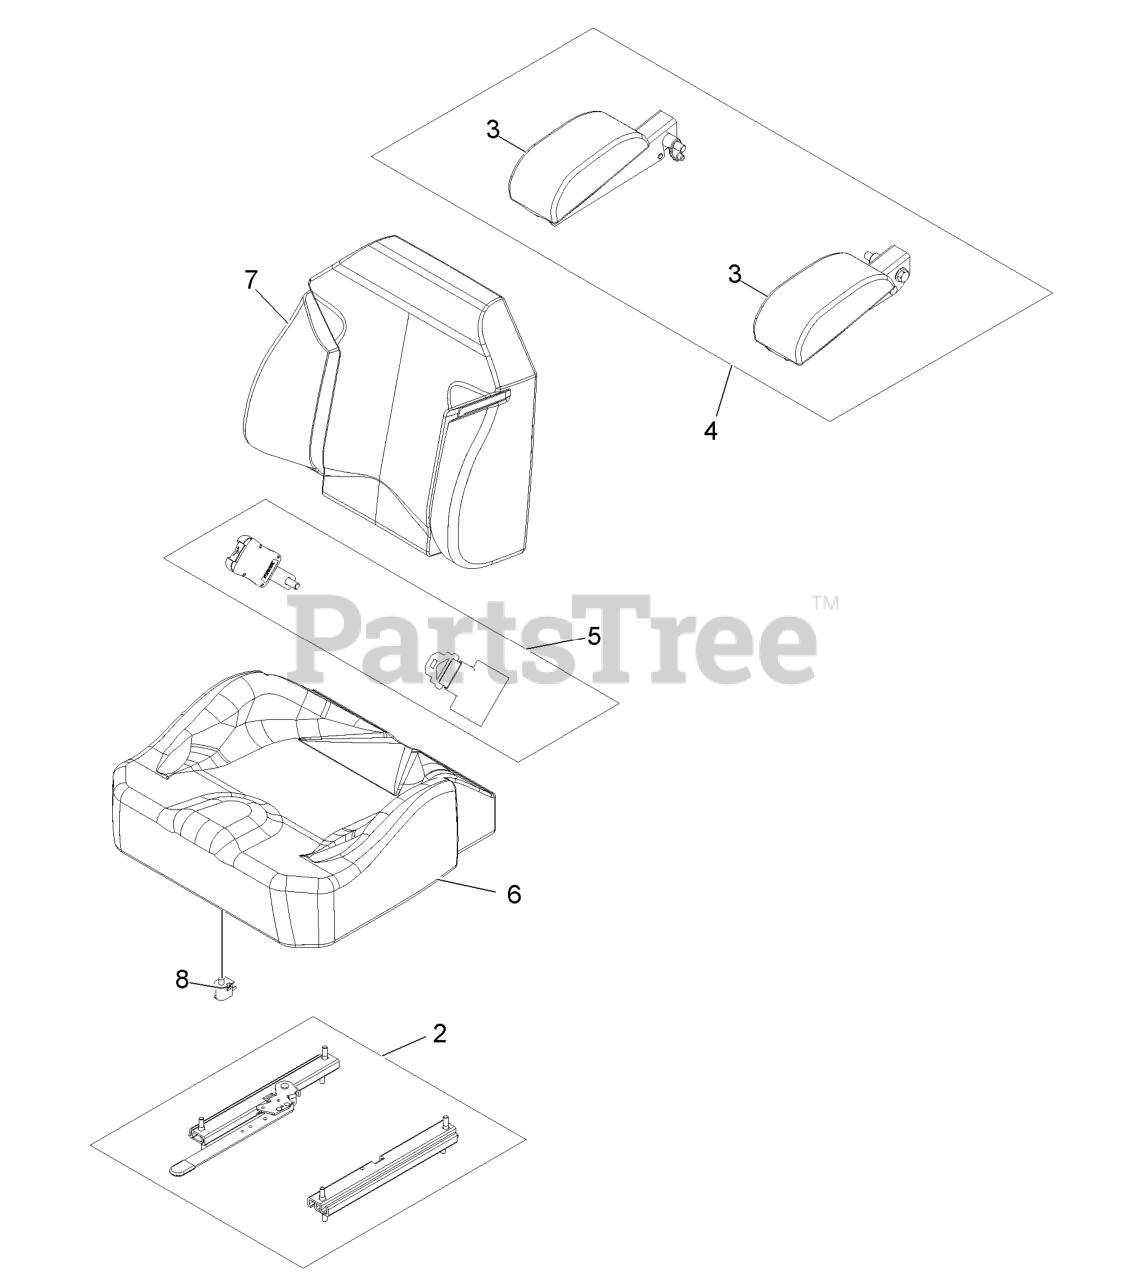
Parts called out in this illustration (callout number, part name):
2	SEAT TRACK SET
3	ARM REST PAD SET
4	ARM REST SET
5	SEAT BELT KIT
6	COVER,CUSHION
7	COVER,BACK
8	SWITCH-BAIL
